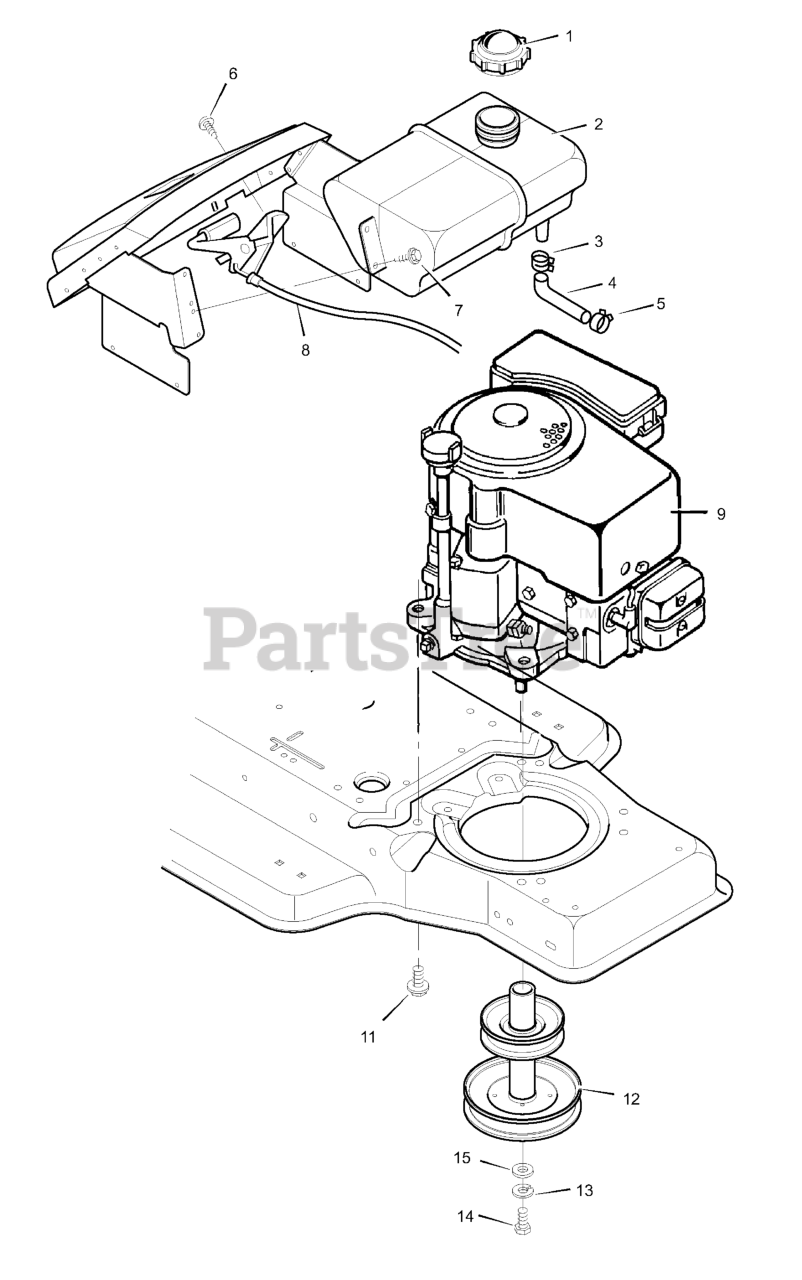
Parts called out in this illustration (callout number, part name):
1	Fuel Cap
2	Fuel Tank
3	Hose Clamp
4	Fuel Line
5	Hose Clamp
8	Throttle Control
9	Engine *
11	Bolt, Engine Mount
12	Stack Pulley Assembly
13	Lockwasher
14	Bolt, Hex
